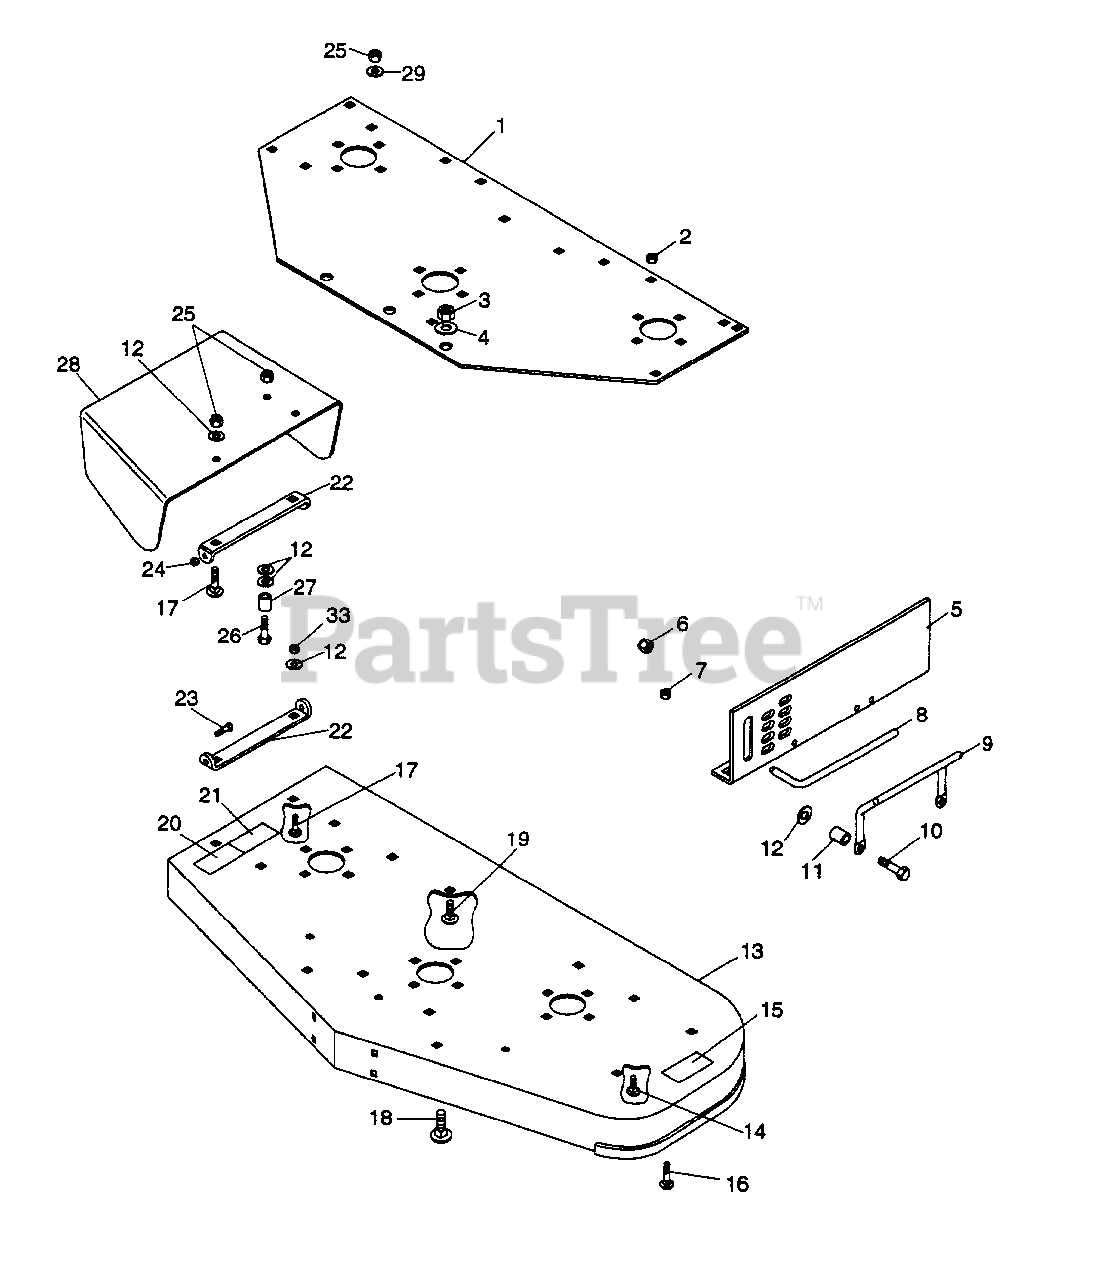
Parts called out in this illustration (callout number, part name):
1	PLT, SUPPORT
2	NUT - LK - NYL .312 - 18 PL
3	NUT - LK - NYL .50 - 13 PL
4	WSHR - FL - STL .531 X 1.250 X .100
5	BRKT, MWR SIDE SPRT L.H.
5	BRKT, MWR SIDE SPRT R.H.
6	NUT - LK - NYL .375 - 16 PL
7	NUT - LK - NYL .312 - 18 PL
8	PIN, MOWER LOCKING
10	BLT - HEX .38 - 16 X 1.75 PL GR 5
11	BUSHING
12	WSHR - FL - STL .406 X .812 X .065 PL
13	WLDMT, 50" MWR FABRICATED
14	BLT, 5/16 - 18 X .625 RDHDSQNK
15	G-DECAL, DANGER FOOT
16	BLT, CARRIAGE 5/16 - 18 X 1.0
17	BLT - RDHDSQNK .38 - 16 X 1.0 PL
18	BLT - RDHDSQNK .50 - 13 X 1.00
19	BLT, CARRIAGE 3/8 - 16 X .75
20	G-DECAL, WARNING EYE
21	G-DECAL, DANGER HAND
22	BRKT, CHUTE
23	BLT - HEX .25 - 20 X .875
24	NUT - LK - NYL .250 - 20 PL
25	NUT - LK - NYL .375 - 16 PL
26	BLT - HEX .38 - 16 X 1.50 PL GR 5
27	BSHG - SLV .407 X .625 X .750 PL
28	SHIELD, SFTY EXT 50" MWR
29	WSHR - FL - STL .406 X .812 X .065
